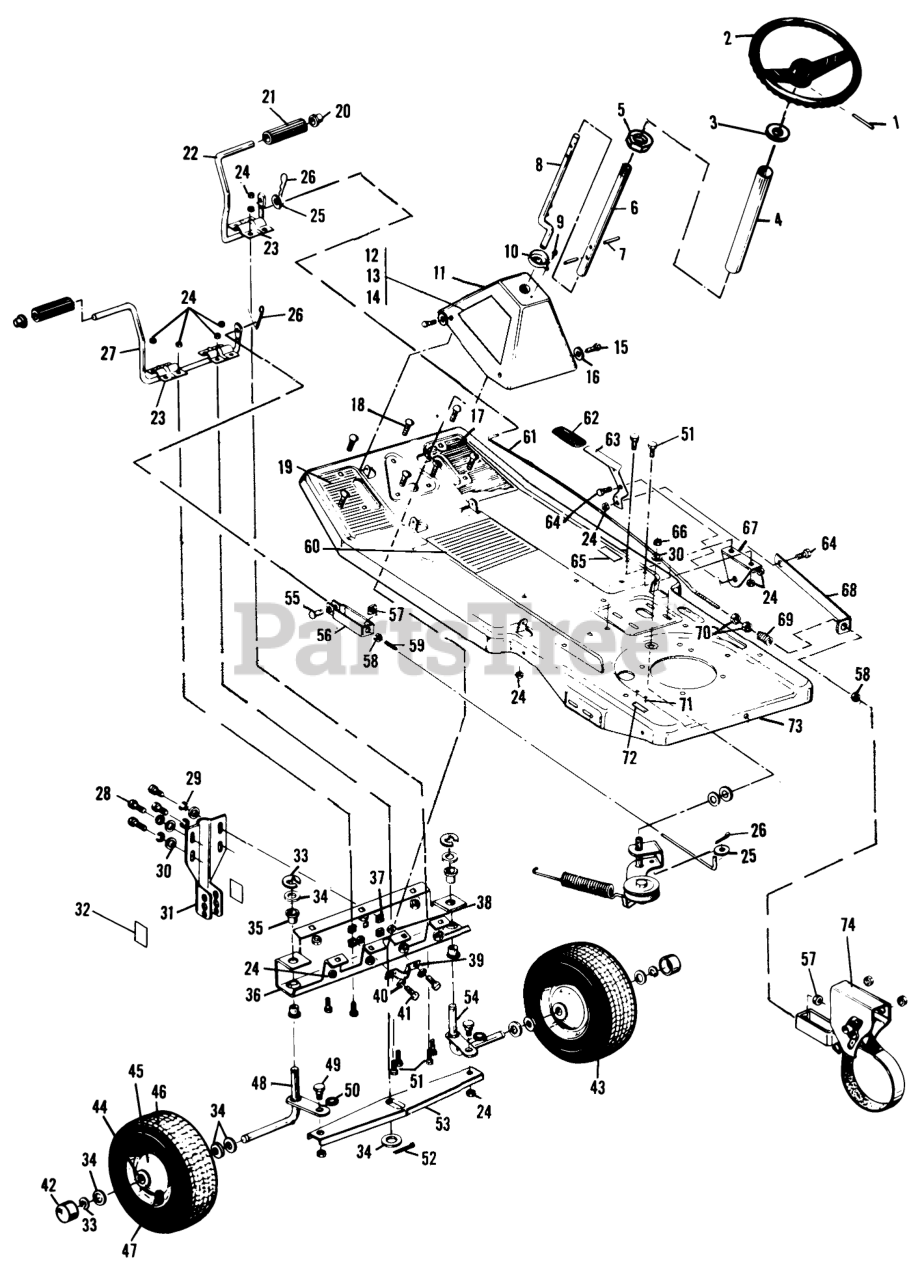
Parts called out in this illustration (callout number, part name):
1	Roll Pin
2	Steering Wheel
3	Washer, Plastic
4	Housing, Steering Tube
5	Nut, Speed
6	Tube, Steering
7	Pin, Spiral
8	Shaft, Steering
9	Screw, S.M. Type, AB No. 10-16 x 1/2 In.
10	Bushing, Steering Tube
11	Quadrant
12	Decal, Cover Plate
13	Decal, Console, L.H.
14	Decal, Console, Front
15	Screw, Taptite, 1/4-20 x 5/8 In.
16	Lockwasher
17	Pad, Footrest, Right
18	Bolt 5/16-18 x 5/8 Carriage
19	Pad, Footrest, Left
20	Speed Nut, Push
21	Pad, PedaI
22	Arm, Brake Pedal
23	Bracket, Pedal Rod
24	Nut-Nylok
25	Washer
26	Cotter Key
27	Arm, Clutch Pedal
28	Bolt 3/8-16 x 1
29	Lockwasher
30	Washer
31	Bracket, Deck Hanger
32	Decal, Deck Hanger
33	"E" Ring
34	Flatwasher, 5/8 In.
35	Bushing, Spindle
36	Bracket, Front Axle
37	Nut, Speed Grip, 3/8-16 Thd
38	Nut-Nylok
39	"U" Bracket
40	Lockwasher
41	Bolt 3/8-16 x 3/4
42	Hub Cap
43	Wheel & Tire Assy, Front, Complete Includes Items 43, 44, 45 & 46
44	Bushing
45	Wheel with Bearings
46	Tire, 4.10-3.50 x 4
47	Valve Stem
48	Spindle, Steering Left
49	Shoulder Bolt
50	Washer, Spring
51	Bolt Hex 5/16-18
52	Cotter Pin, 3/16 x 1 1/4 In.
53	Link, Steering
54	Spindle, Steering Right
56	Clevis
57	Nut
58	Nut 1/4-20 Keps
59	Rod, Clutch
60	Pad, Footrest Center
61	Rod, Brake
62	Grip, Parking Brake
63	Lever, Parking Brake
64	Shoulder Bolt
65	Decal, Parking Brake
66	Nut
67	Bracket, Parking Brake
68	Strap, Parking Brake
69	Spring
70	Nut 1/4-20
71	Drive Screw, No. 6 x 5/16 In.
72	Plate, Model Number
73	Main Frame
74	Brake, Assembly, Complete
